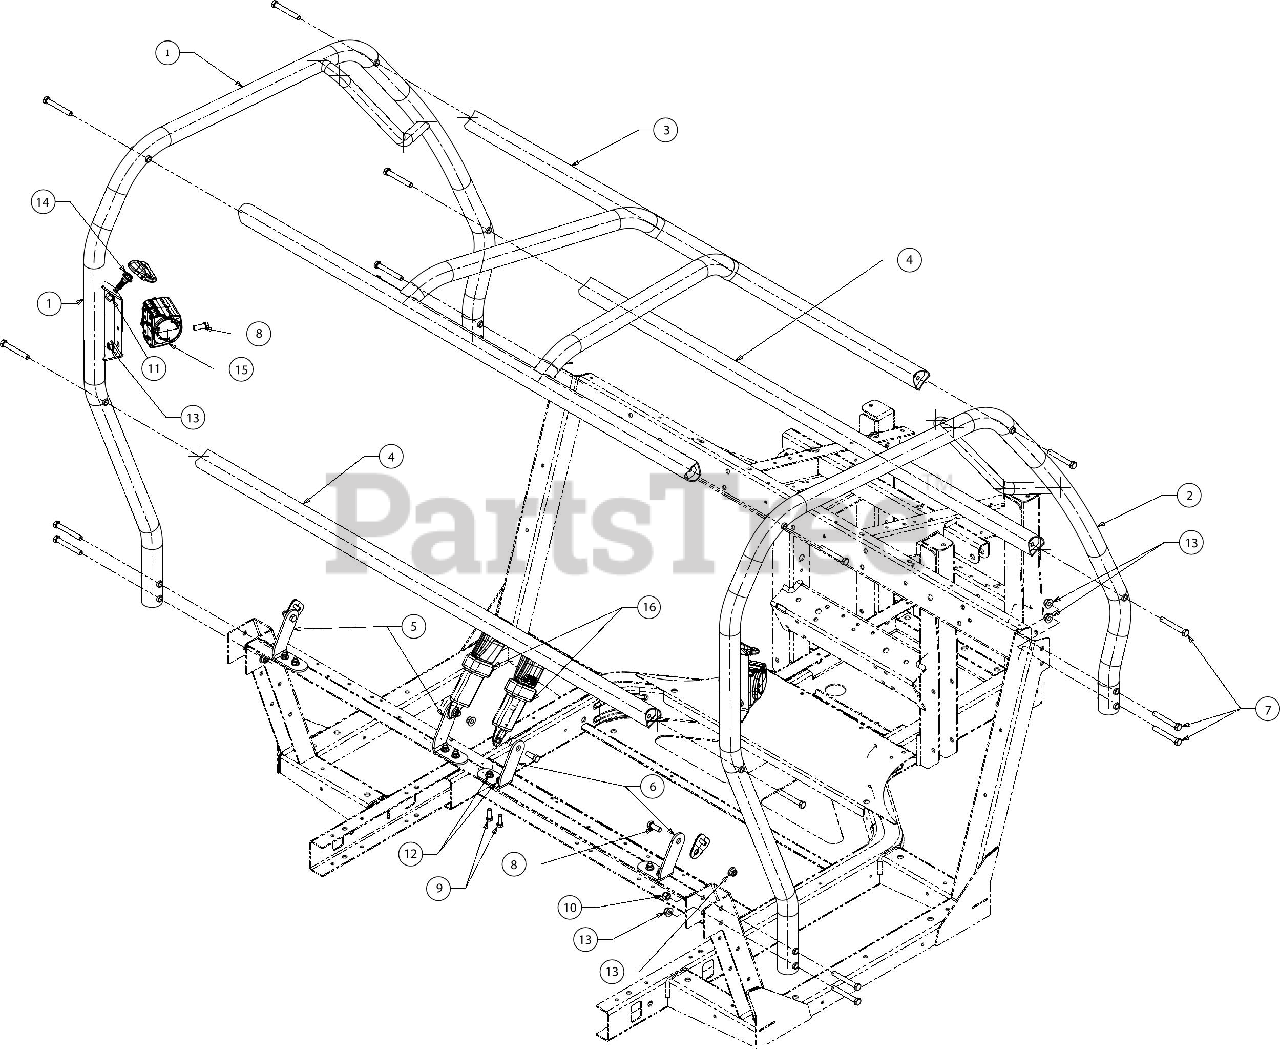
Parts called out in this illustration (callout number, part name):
1	FRAME ASSEMBLY OPS (LH)
2	FRAME ASSEMBLY OPS (RH)
3	FRAME ASSEMBLY OPS ROOF
4	FRAME ASSEMBLY-OPS FRONT
5	SEAT BELT BRACKET
6	SEAT BELT BRACKET
7	SCREW 3/8-16 x 2.75 GR5
8	SCREW 3/8-16 x 1 GR5
9	SCREW 5/16-18 x .875 GR5
10	HEX NUT INS L-3/8-16
11	FLANGE LOCK NUT
12	FLANGE LOCK NUT 5/16-18
14	SHOULDER BOLT 7/16-20
15	3-POINT SEAT BELT
16	3-POINT SEAT BELT
